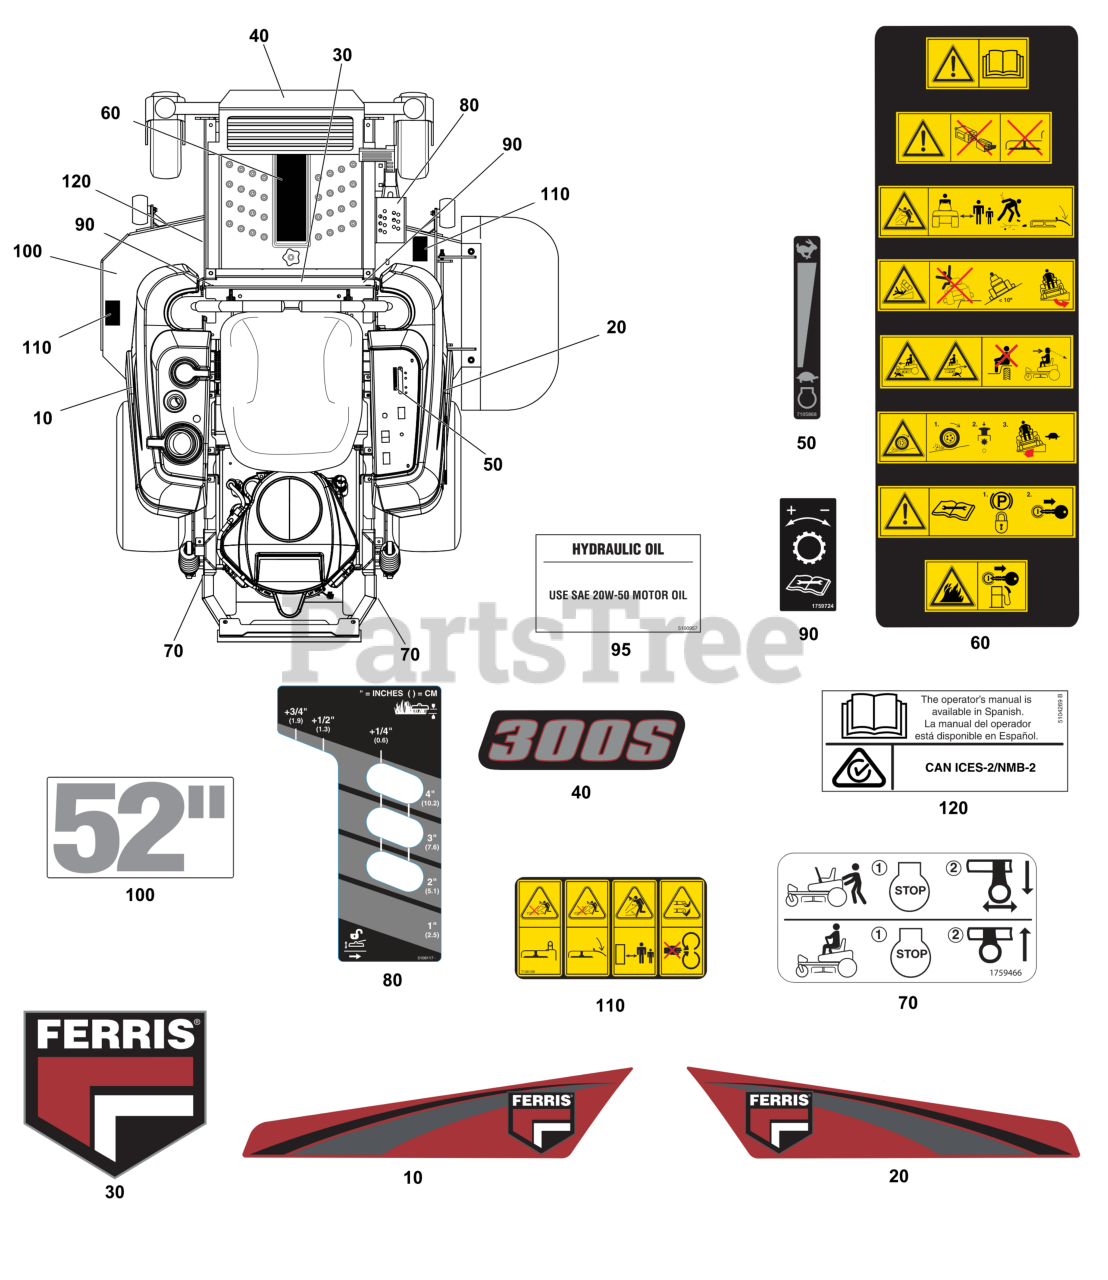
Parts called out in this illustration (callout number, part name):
10	DECAL, BRAND
20	DECAL, BRAND
30	DECAL, BRAND
40	DECAL, Model
50	DECAL, ENGINE SPEED
60	DECAL, WARNING/SAFETY
80	DECAL, CUTTING HEIGHT
90	DECAL, Tracking Adjustment - ZT
95	DECAL, Oil
100	DECAL, 52
110	DECAL, DISCHARGE
